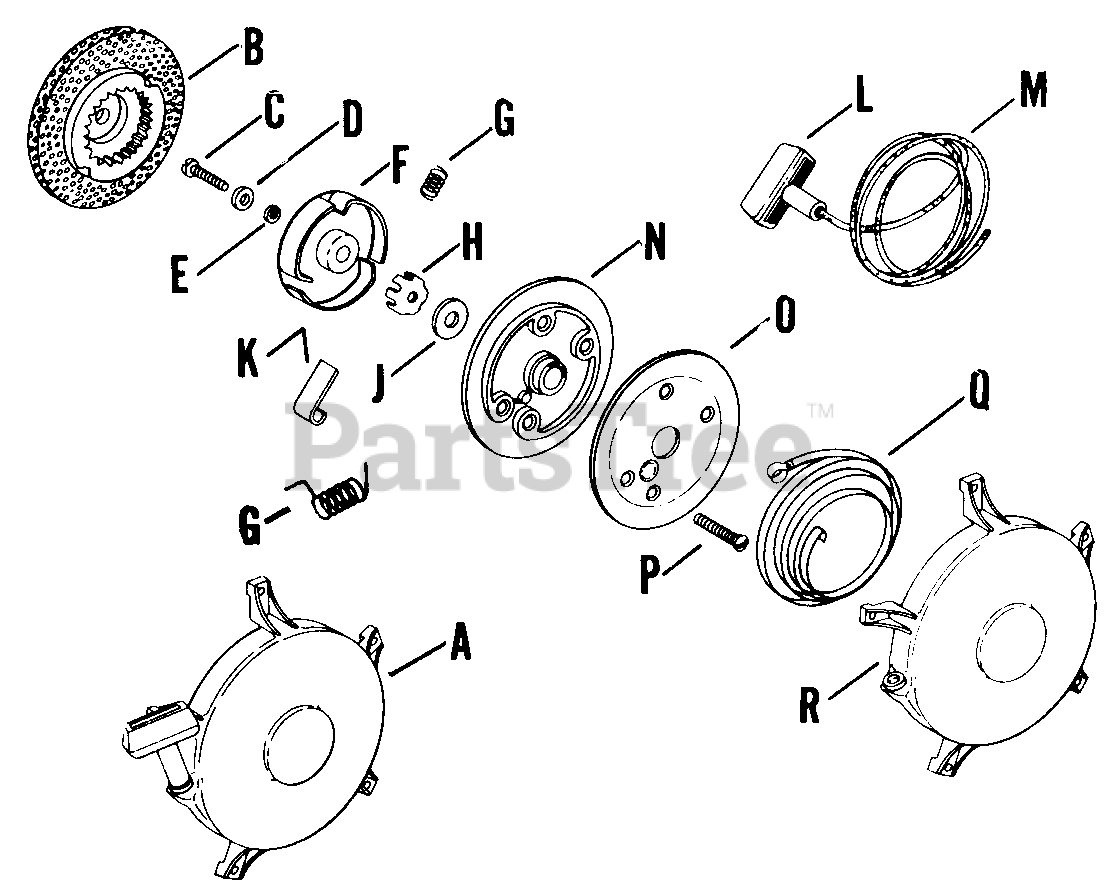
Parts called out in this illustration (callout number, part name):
A	STARTER - USE 41 165 01
B	CUP - USE 41 071 02
D	WASHER - DISCONTINUED
F	RETAINER
K	DOGS - DISCONTINUED
Q	SPRING-(#DSC)
R	HOUSING - DISCONTINUED
